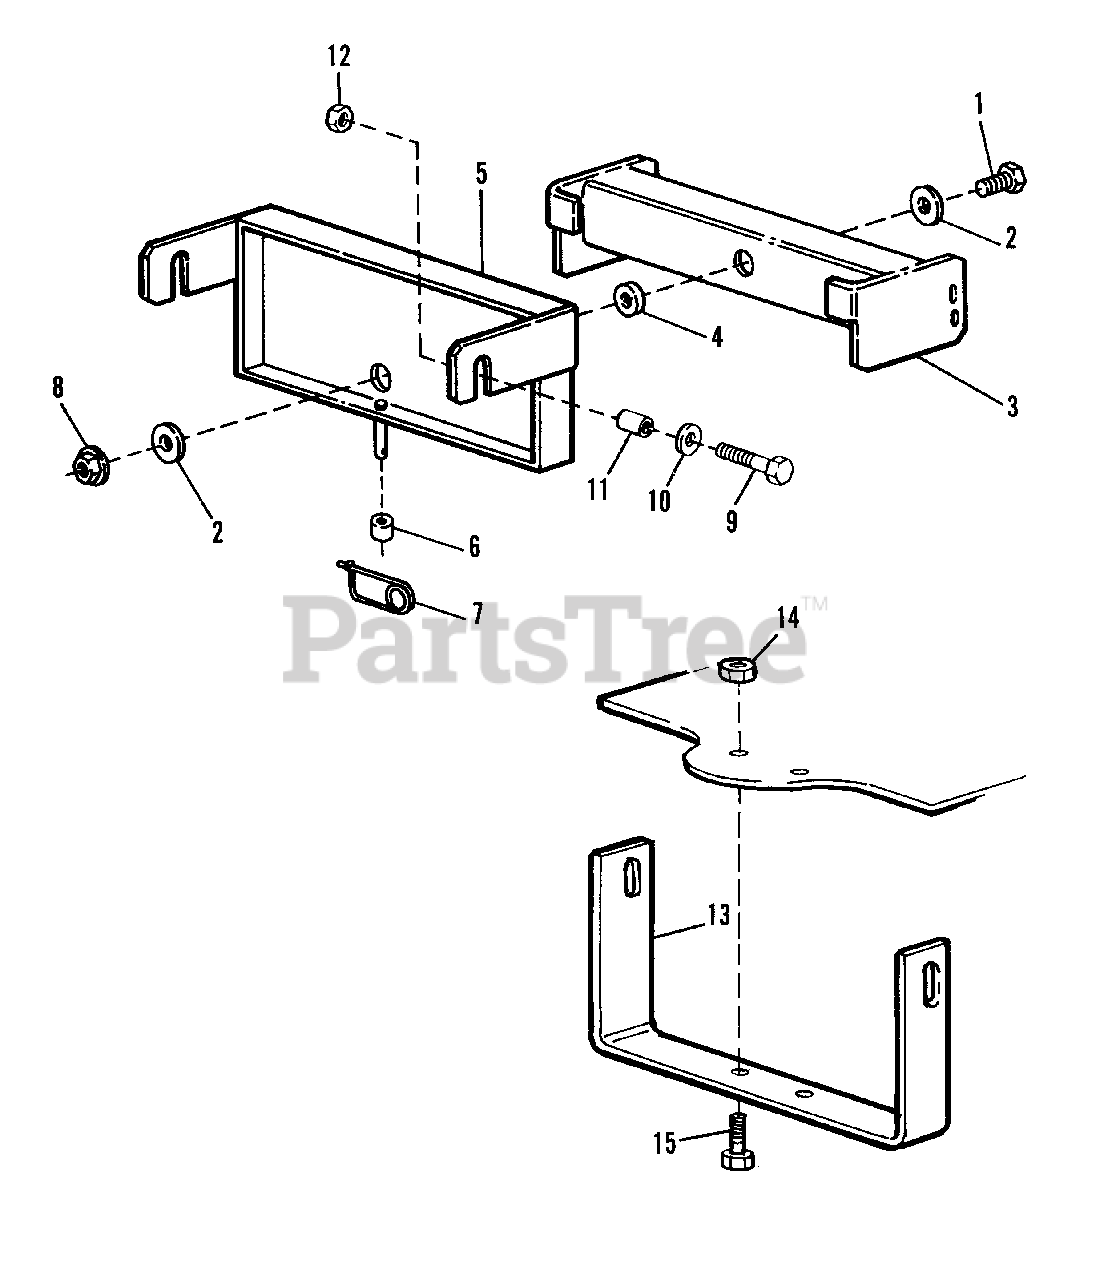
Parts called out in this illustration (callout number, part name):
2	WASHER, Plain, 1/2
3	PIVOT, Plate, Hitch
5	SUPPORT, Plate, Hitch
7	PIN, Safety
8	LOCKNUT, Hex , Flange, 1/2-13
9	CAPSCREW, 3/8-16 x 1-1/4
10	WASHER, Plain, 3/8
12	NUT, Hex, Lock, 3/8-16
13	BRACKET, "U" Hitch (Mfg. No. 1692031 Only)
14	NUT, Hex, Lock Esna, 1/2-13 (Mfg. No. 1692031 Only)
15	CAPSCREW, Hex, 1/2-13 x 1-1/2 (Mfg. No. 1692031 Only)
